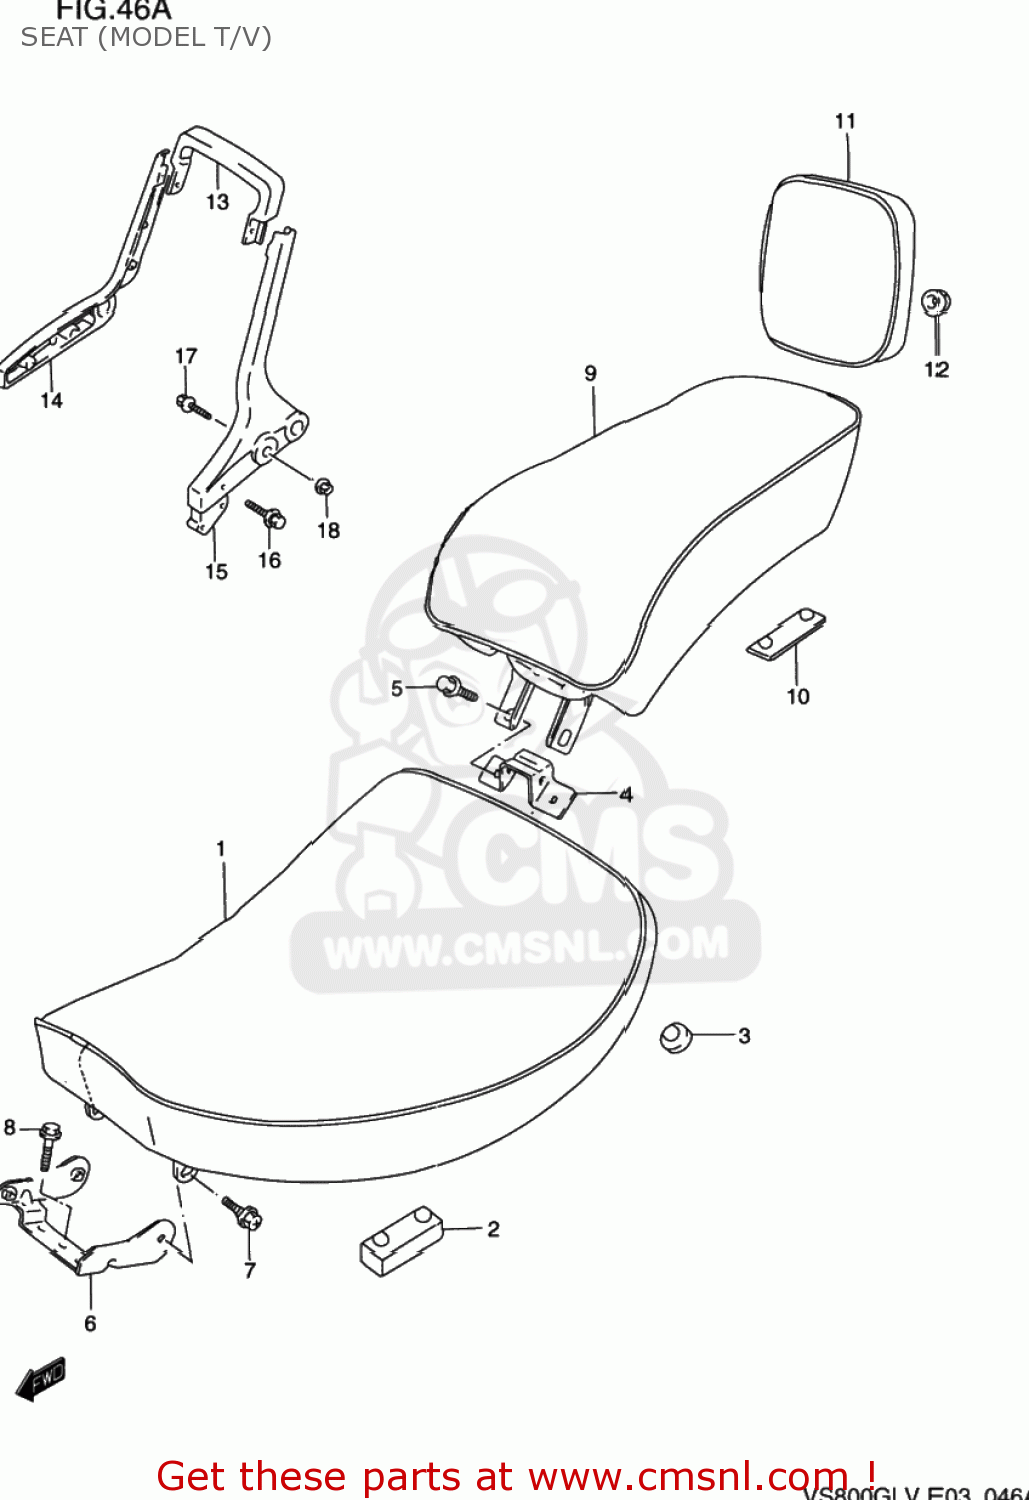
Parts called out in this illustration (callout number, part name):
1	SEAT ASSY
2	CUSHION,SEAT
3	CUSHION
4	PLATE,FR SEAT HOOK & RR
5	BOLT(6X16)
6	BRACKET,SEAT FR
7	BOLT(6X16)
8	BOLT
9	SEAT ASSY,PILLION
10	CUSHION
11	PAD ASSY,SEAT
12	CUSHION
13	HANDLE,PILLION RIDER UPR
14	HANDLE,PILLION RIDER,R
15	HANDLE,PILLION RIDER
16	BOLT
17	BOLT
18	NUT
